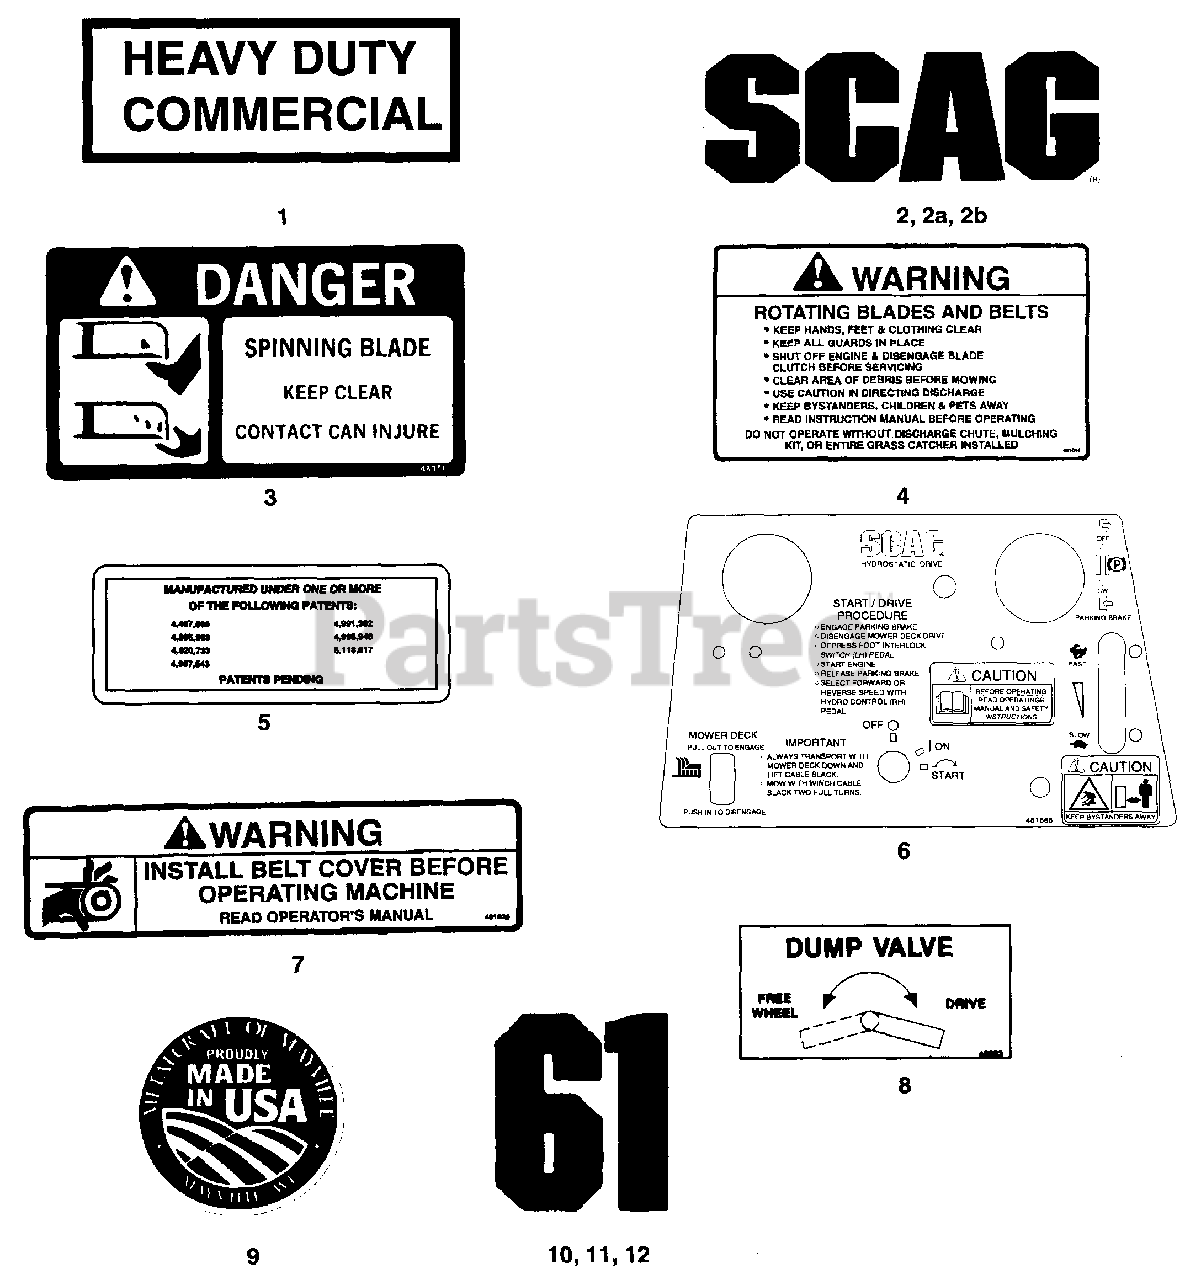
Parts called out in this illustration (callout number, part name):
1	Decal, Heavy Duty Commercial
2	Decal, Scag Logo (Cutter Deck)
2A	Decal, Scag Logo (Battery Box Front)
2B	Decal, Scag Logo Seatback
3	Decal, Danger-Spinning Blades
4	Decal, Warning-Rotating Blades
5	Decal, Patent
6	Decal, Instrument Panel
7	Decal, Warning-Belt Cover
8	Decal, Dump Valve
9	Decal, Metalcraft-Made In USA
10	Decal, 52
11	Decal, 61
12	Decal, 72
